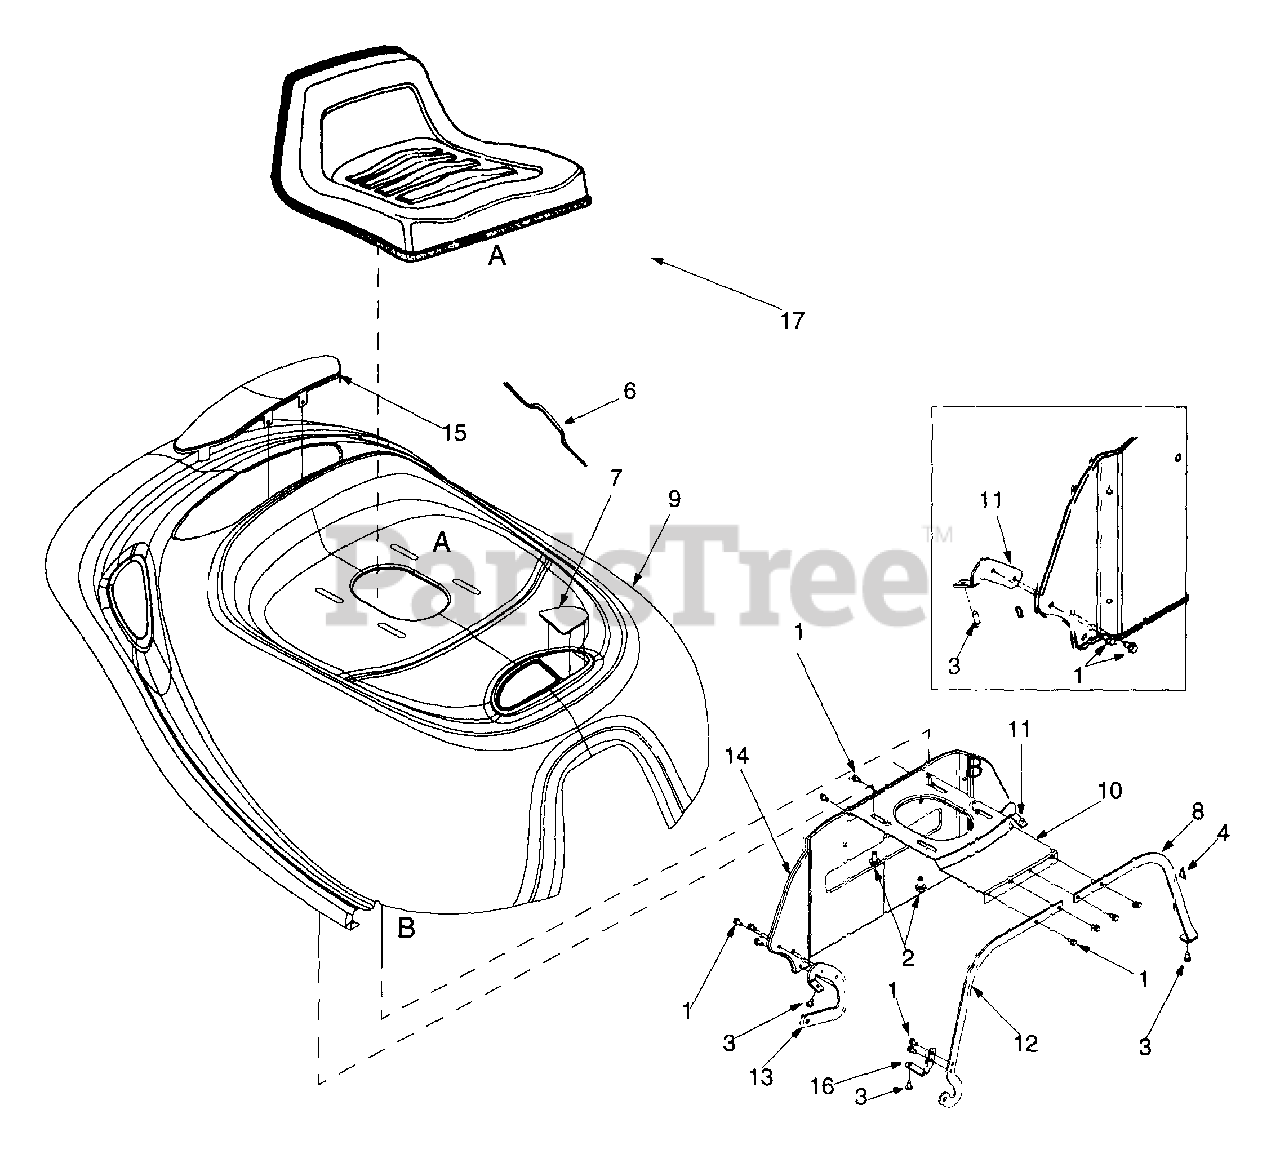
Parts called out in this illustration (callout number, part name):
1	Hex Hd. TT Screw 1/4-20 x 0.5
2	Hex Washer Hd. TT Screw 3/8-16 x 0.62
3	Torx Head AB screw 1/4-14 x 0.625
4	Rod End Grip
6	Trim strip
7	Grass Bag Lens
